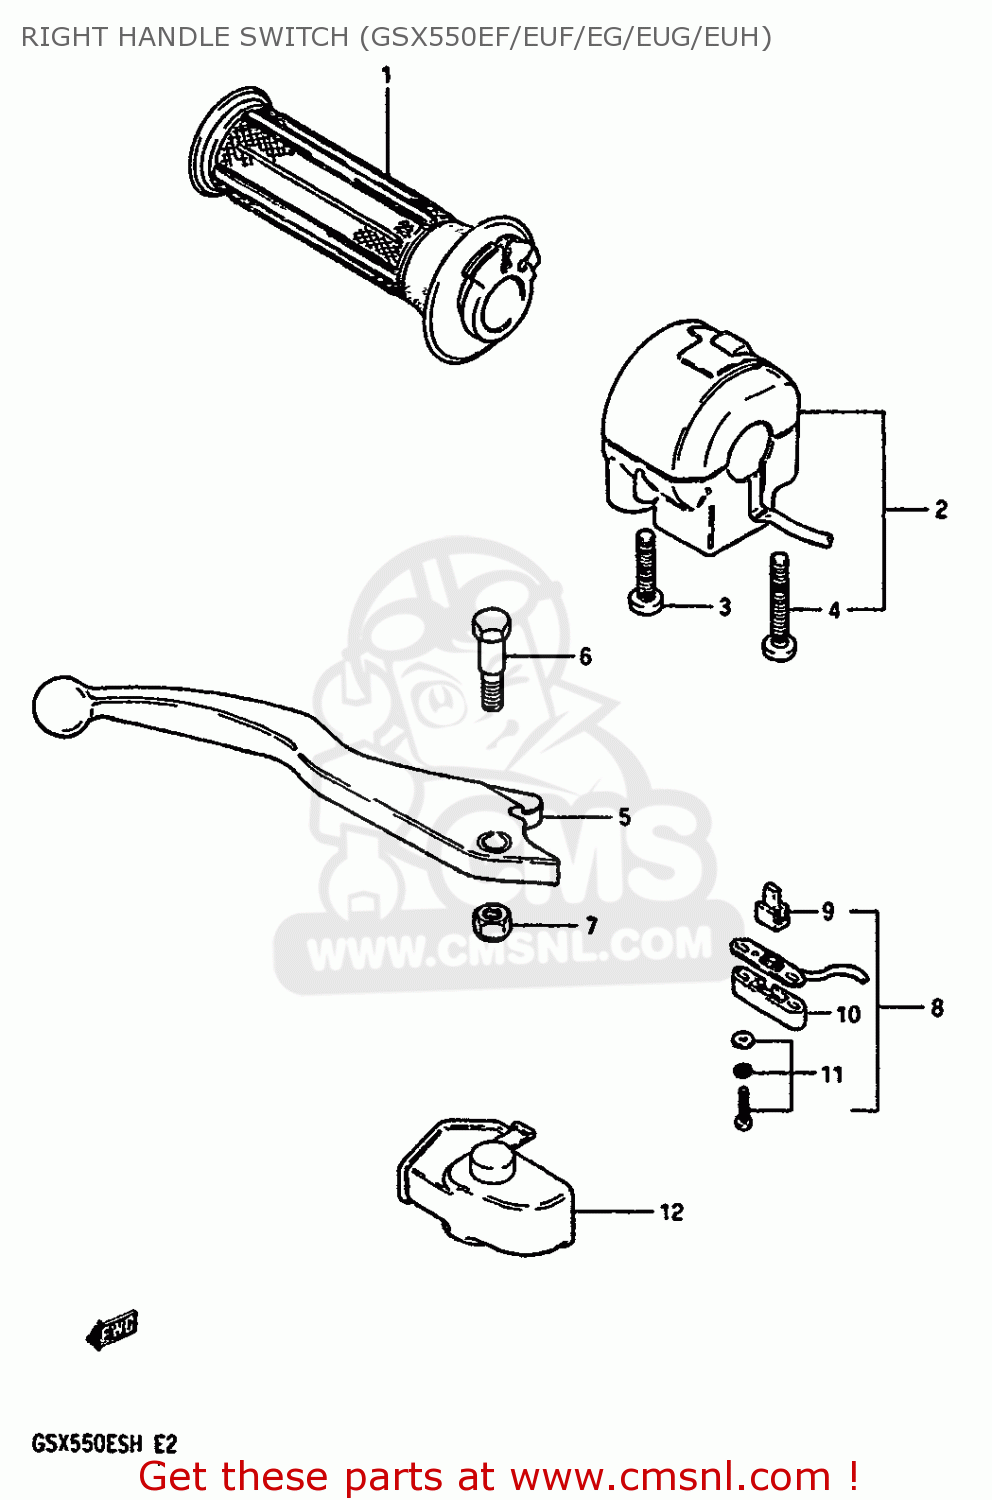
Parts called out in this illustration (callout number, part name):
1	GRIP,THROTTLE
2	SWITCH ASSY,HANDLE
3	SCREW
4	SCREW
5	LEVER,BRAKE
6	BOLT,LEVER PIVOT
7	NUT
8	SWITCH ASSEMBLY
9	CONTACT,SWITCH
10	COVER,FR BK TERMINAL BASE
11	SCREW
12	COVER,BRAKE LEVER
